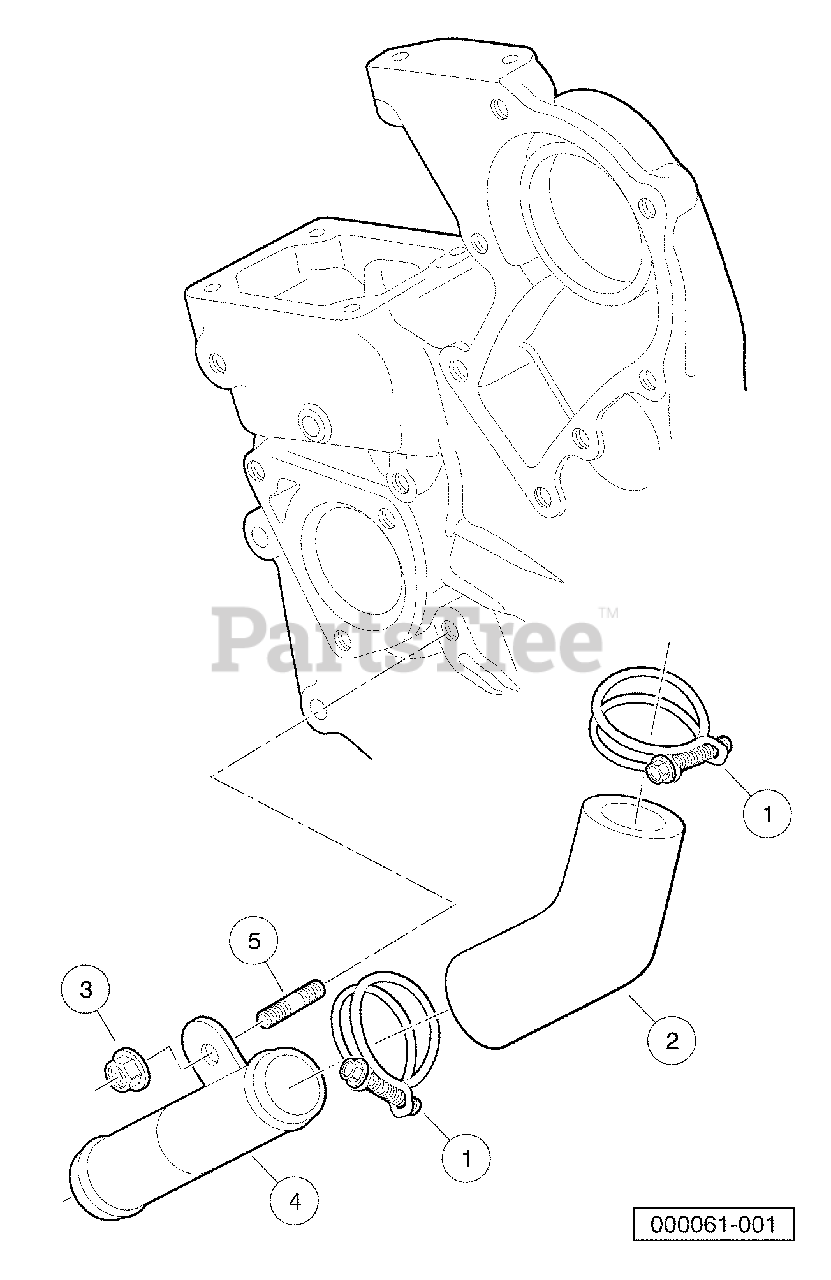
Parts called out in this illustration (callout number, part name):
1	Band, Pipe, with Nut
2	Pipe, Water, Bent
3	Nut, Flange, M6
4	Pipe, Water, Bent
5	Stud, M6 X 15
